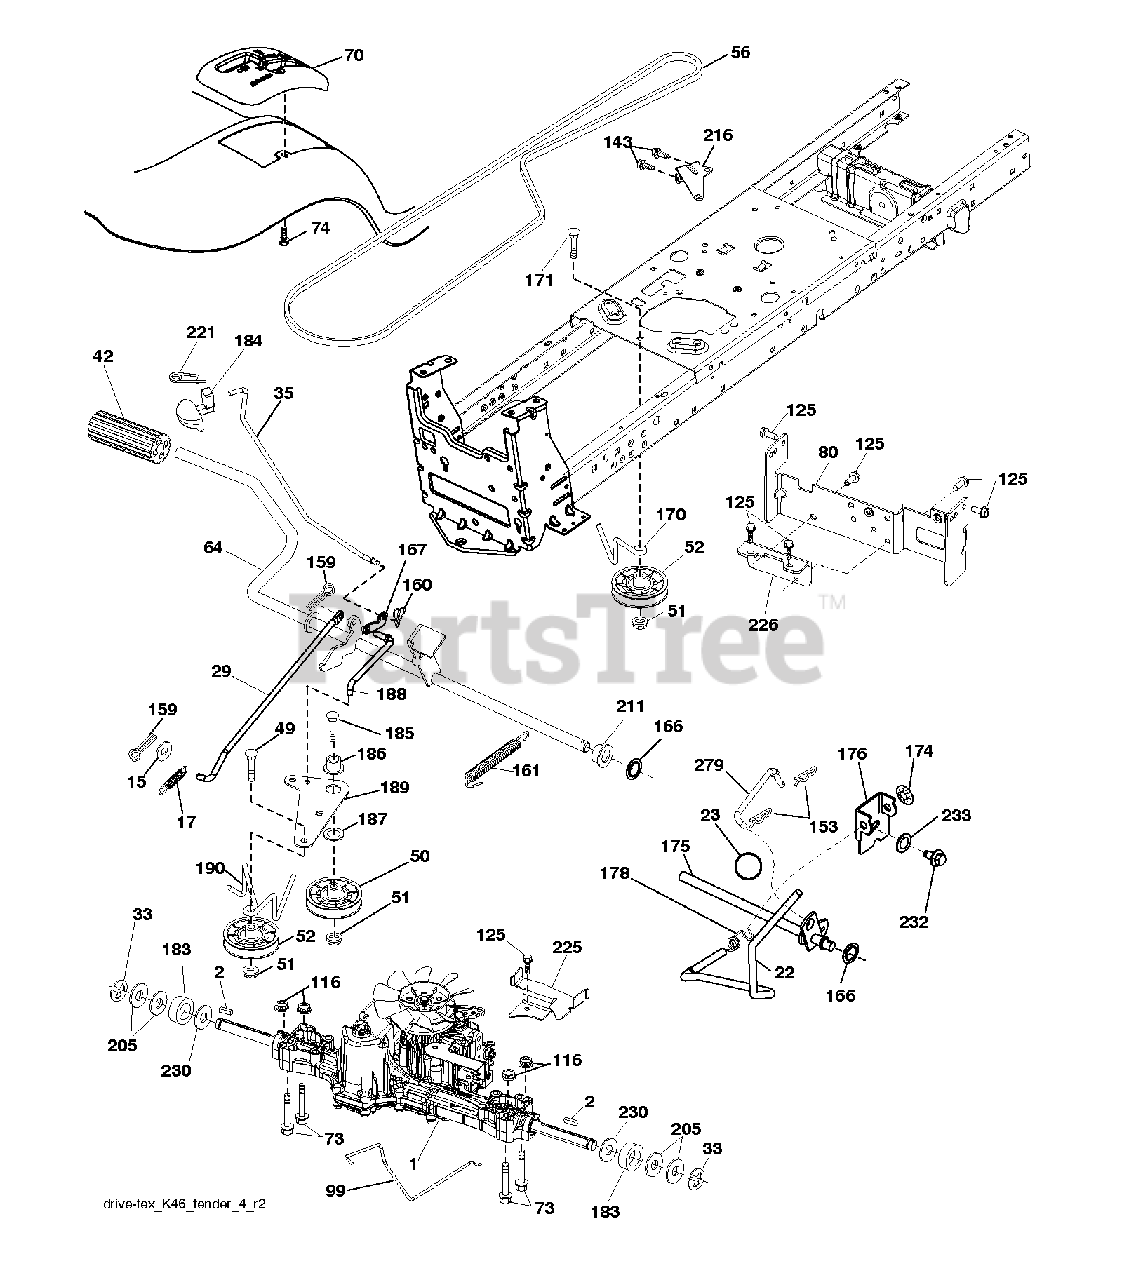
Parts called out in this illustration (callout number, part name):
2	SQUARE KEY
17	SPRING.BRAKE.K46.GREEN
22	ROD.SHIFT.FENDER.TLT.2006
29	ROD.BRAKE.K46
33	E-RING LT
35	ROD.BRAKE.PARKING.LT.T
49	BOLT
50	IDLER.FLAT.910.OFFSET
51	NUT LOCK FLG 3/8-16 UNC
52	IDLER.V-GROOVE.910.OFFSET
56	V-BELT.MOWER.92.40.42/K46
64	SHAFT.ASM.PEDAL.BRAKE.
70	CONSOLE.SHIFT.STL.HYD.BLACK
73	BOLT HEX 5/16-18 GR 5
74	SCREW.HI-LO.CONSOLE
80	STRAP TORQUE
99	ROD.SPRING.BYPASS.K46.LT.Z
116	NUT LOCK HEX FLANGE 5/16-18
125	SCREW
143	SCREW LT
159	COTTER PIN
160	RETAINER CLIP
161	SPRING, RETURN LT
166	NUT.PUSH.625
167	LATCH.BRAKE.SPRING
170	KEEPER.V-IDLER.CENTER.
171	BOLT
174	NUT.PUSH.500.2006
175	SHAFT ASM SHIFT
176	ARM.CLEVIS.ROD.SHIFT
178	SPRING.SHIFT.GT2006
183	SPACER AXLE
186	SPACER.RETAINER
187	WASHER 12/32X2X10GA
188	LINK.CLUTCH.GROUND.DRIVE
189	BELLCRANK.GROUND.DRIVE.TEX.
190	KEEPER.BELLCRANK.DRIVE
211	BUSHING.SHAFT.BRAKE.HAND
216	BRACKET.PULLEY.IDLER.W/TEX
221	RETAINER.SPRING.CLIP.H
225	KEEPER.BELT.TRANSAXLE.K46
226	BRACKET.MOUNT.TORQUE.K46.TLT
230	WASHER.HARDENED
232	BOLT FIN HEX 7/16-14 X 1
233	WASHER SERRATED
279	LINK.SHIFT.T/A.K46.FEND.TX
